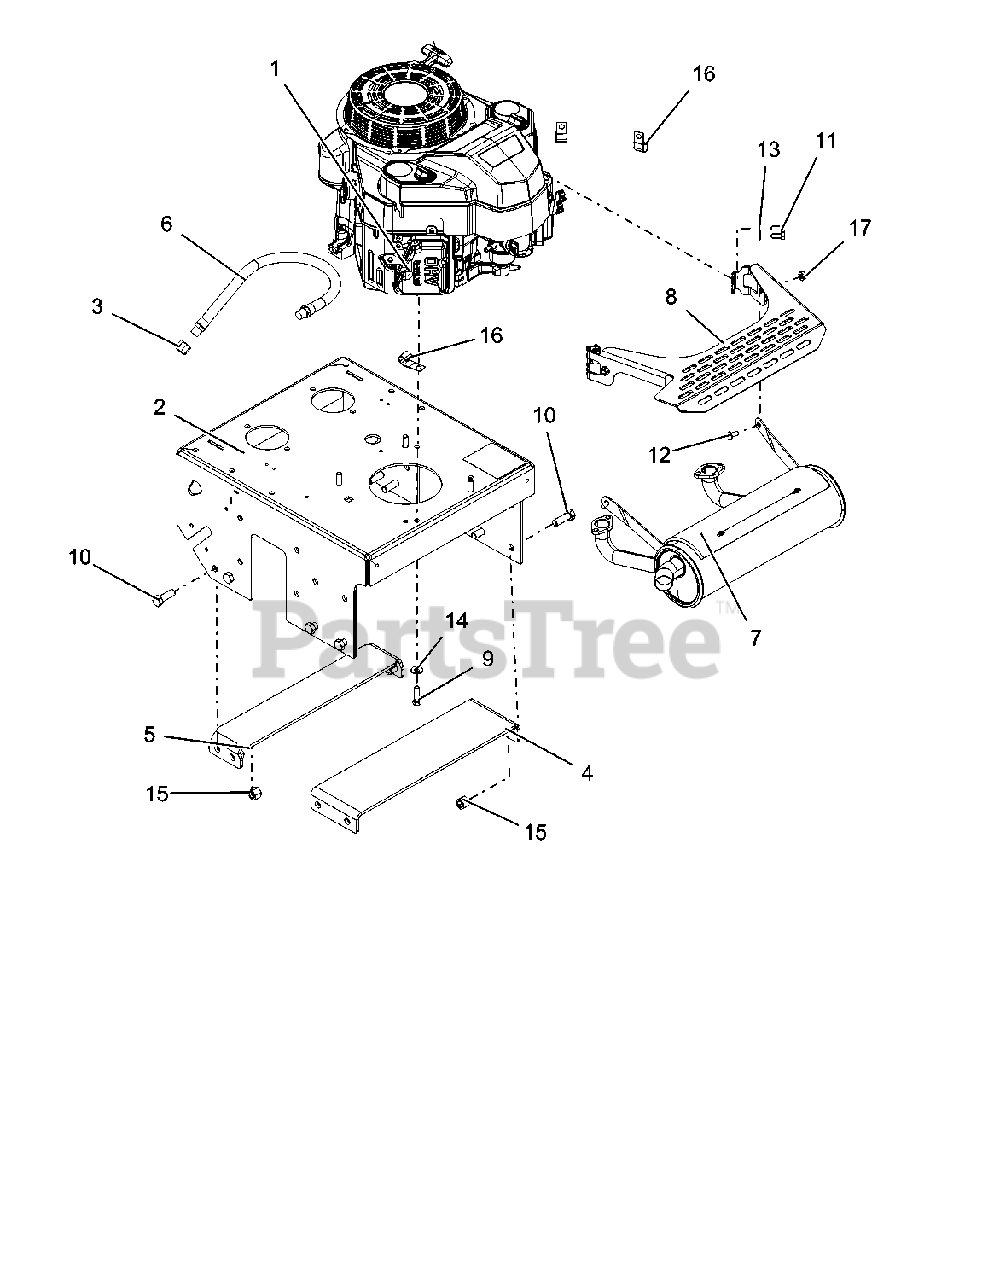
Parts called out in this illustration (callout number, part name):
1	ENGINE, KAWASAKI FS481
2	ASM, FRAME W/DECALS 36" GRAVELY
3	PIPE, CAP 3/8 NPT FEMALE
4	PLATE, ENGINE BED FRONT 36-RED
5	PLATE, ENGINE BED REAR 36-RED
6	DRAIN, M20 OIL
7	EXHAUST, KAWASAKI FS
8	SHIELD, MUFFLER-BLACK
9	BLT-HEX .38-16X1.25 GR5 YWZC NYTORQ
10	BLT-HEX .50-13X1.50 GR5 YWZC
11	@BLT-HEX M8-1.25X20 YWZC
12	SCR - HEX -FL M8X1.25X16 10.9
13	WSHR-LK .31X.078 REG YWZC
14	WSHR, 3/8" SPRING DISC
15	NUT-LK-NYL .50-13 YWZC
16	P-CLIP, .500 INSULATED
17	LOCKNUT, M8 X 1.25, FLANGED ZN
